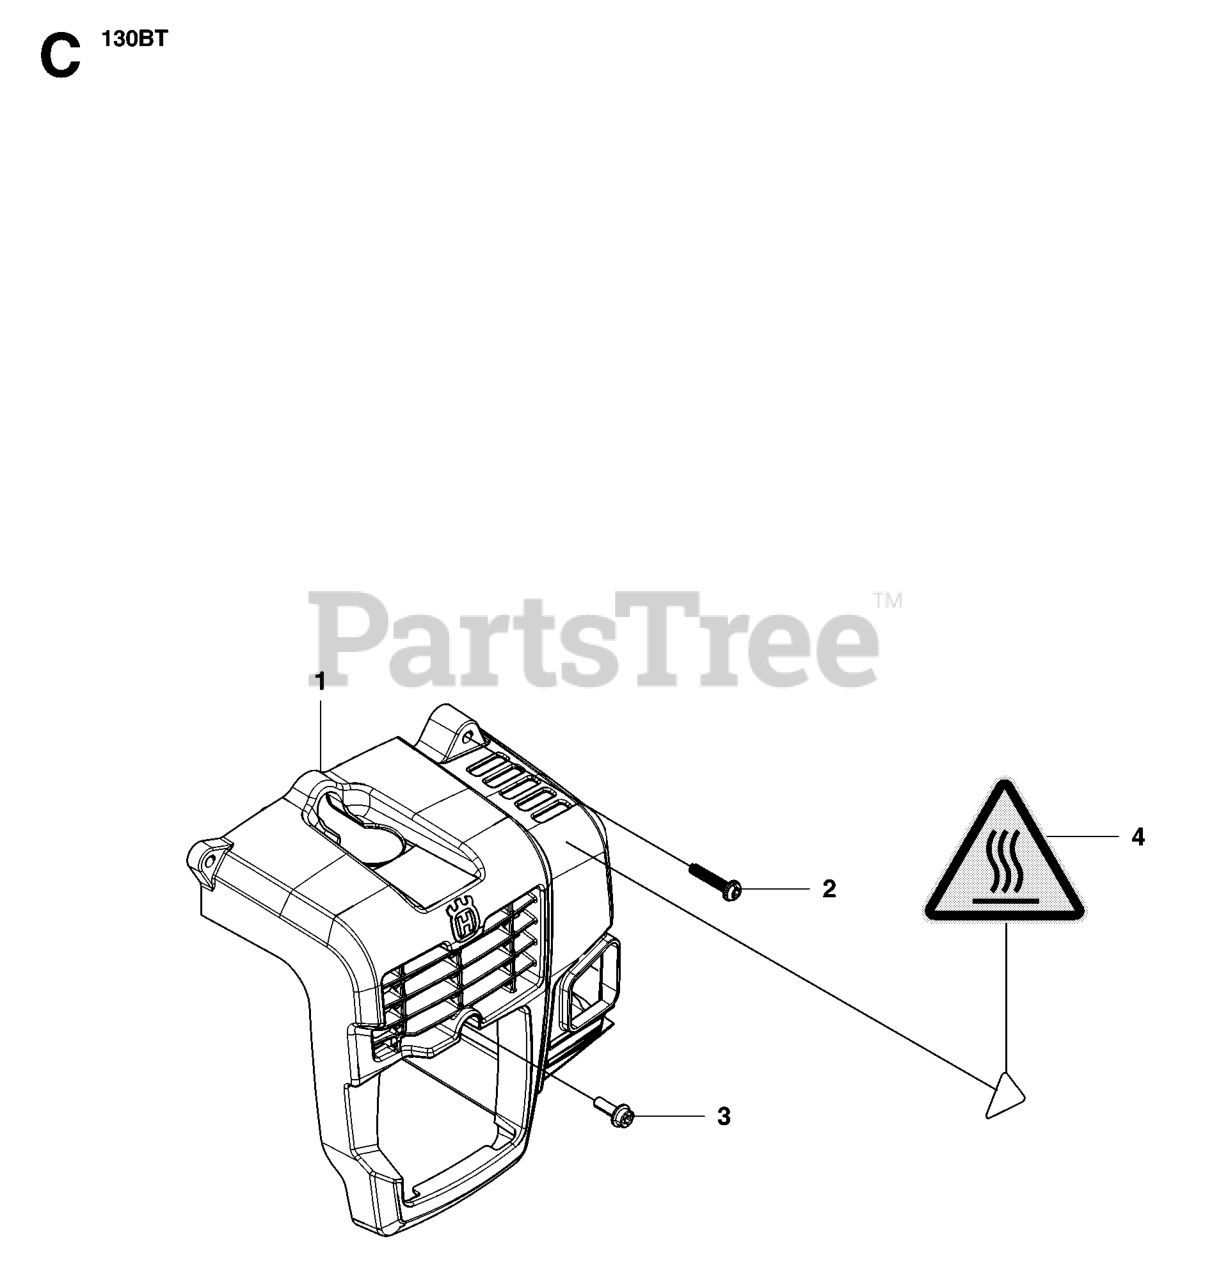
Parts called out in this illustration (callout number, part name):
1	ENGINE COVER
2	SCREW
3	BOLT
4	RP_LABEL, HOTMARK
